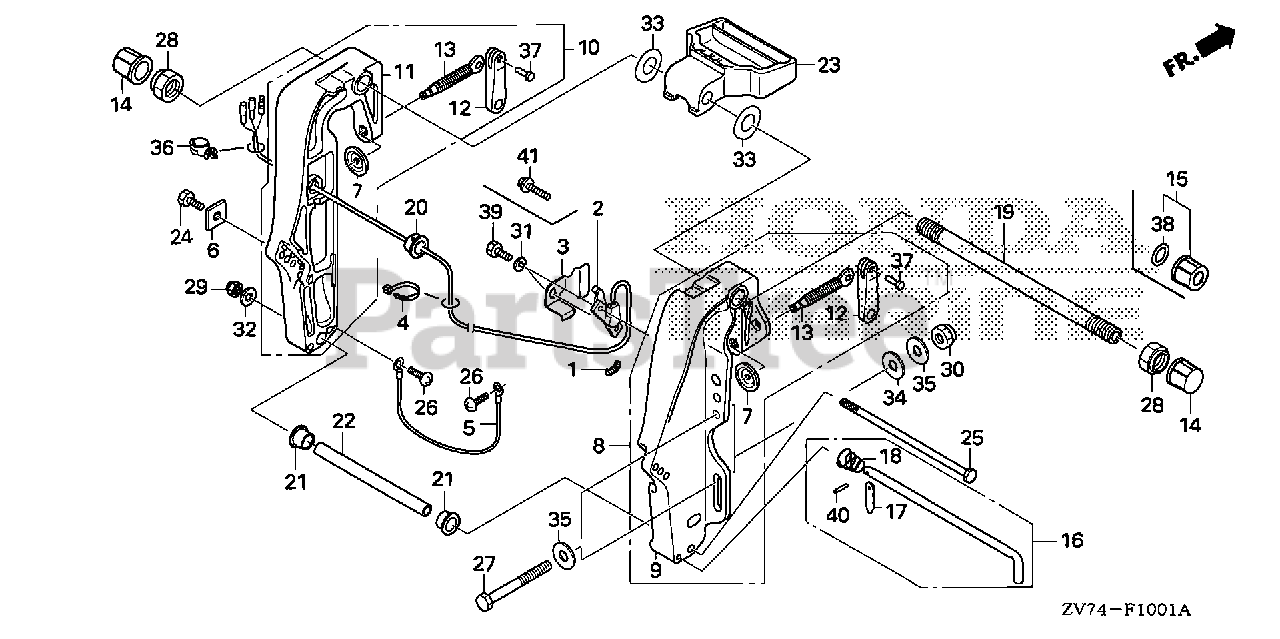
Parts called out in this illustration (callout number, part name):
5	WIRE, LEAD (1.5X170MM)
6	METAL, ANODE
7	PLATE, PUSH
8	BRACKET, R. STERN *NH282MU* (OYSTER SILVER METALLIC-U)
9	BRACKET, R. STERN *NH282MU* (OYSTER SILVER METALLIC-U)
10	BRACKET, L. STERN *NH282MU* (OYSTER SILVER METALLIC-U)
11	BRACKET, L. STERN *NH282MU* (OYSTER SILVER METALLIC-U)
12	GRIP, CLAMP
13	SCREW, CLAMP
14	CAP, TILTING BOLT
16	ROD, ADJUSTING
17	STOPPER, ROD
18	SPRING, ADJUSTING ROD
19	SHAFT, TILTING
21	BUSH, CYLINDER (LOWER)
22	COLLAR, CYLINDER (LOWER)
23	HANDLE, CARRYING
24	BOLT, FLANGE (6X12)
25	BOLT, HEX. (8X203)
26	SCREW, PAN (6X8)
28	NUT, SELF-LOCK (7/8-14UNF)
29	NUT, SELF-LOCK (8MM)
32	WASHER, PLAIN (8MM)
33	WASHER, WAVE (22MM)
37	RIVET (4X22.6)
40	PIN, SPRING (2.5X8)
